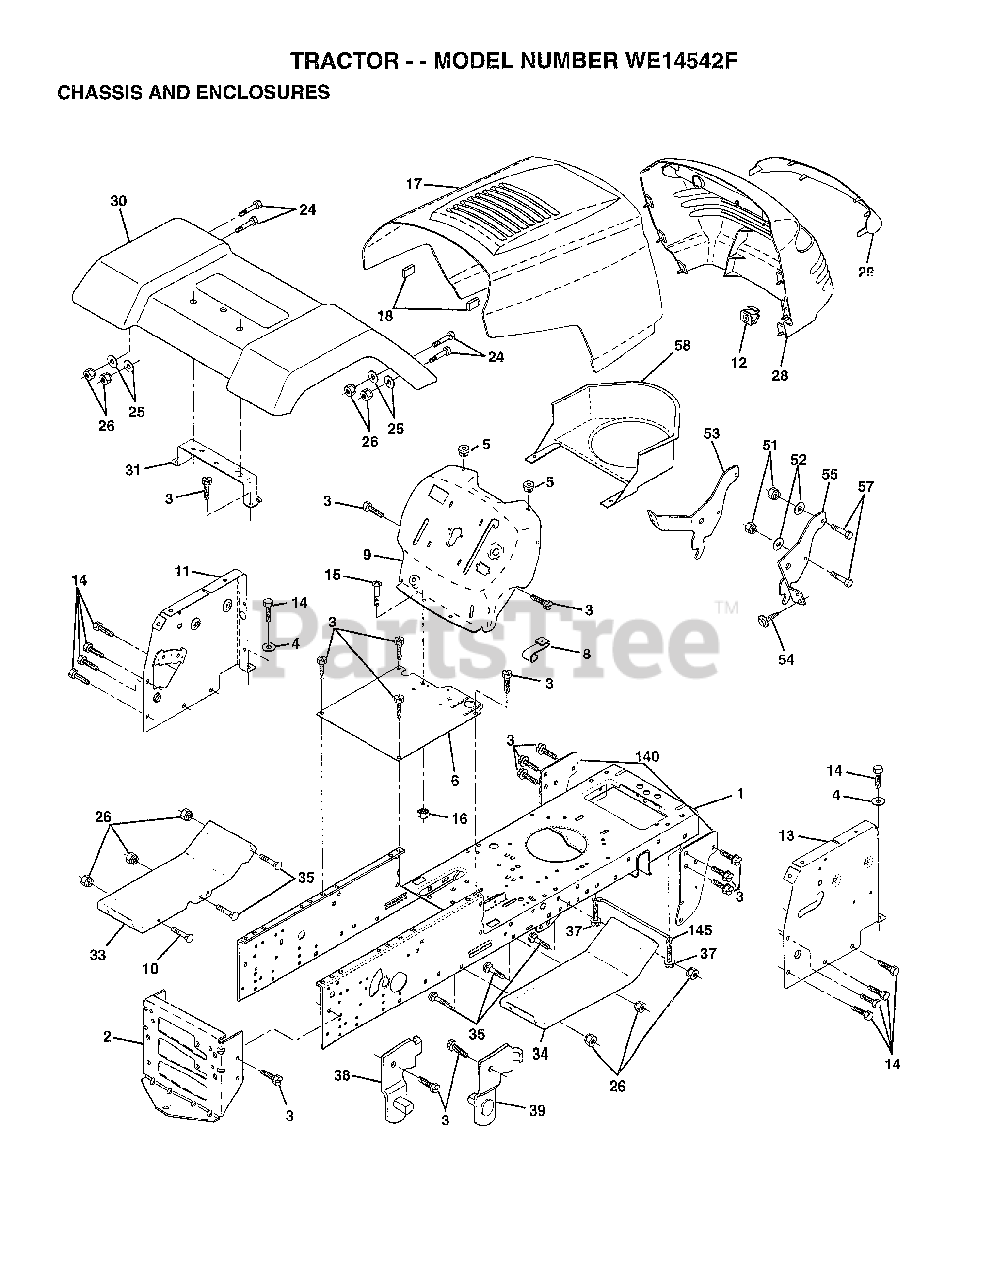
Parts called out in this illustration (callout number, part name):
1	CHASSIS ASM
3	SCREW
4	WASHER
5	BUMPER-HOOD/DASH
6	SADDLE-SILKSCREEN
8	CLIP.RETAINER
9	DASH.SILKSCREENED
11	"PANEL-DASH,LH"
12	CLIP.TINNERMAN
14	SCREW LT
15	SCREW
17	HOOD.STEEL.ASSY
24	BOLT
25	WASHER
26	NUT
28	GRILLE-MS428
29	LENS GRILLE
31	BRKT FENDER
33	FOOTREST.LH.PERF.
34	FOOTREST.RH.PERF.
35	BOLT
37	SCREW LT
38	BRACKET ASM LH
39	BRACKET ASM RH
51	NUT
52	WASHER
53	BRACKET.GRILLE.LH
54	SCREW.HEX.WS.HD
55	BRACKET.GRILLE.RH
58	AIR DUCT
140	BRKT SUSPENSION
145	"ROD POVOT,CHASSIS"
